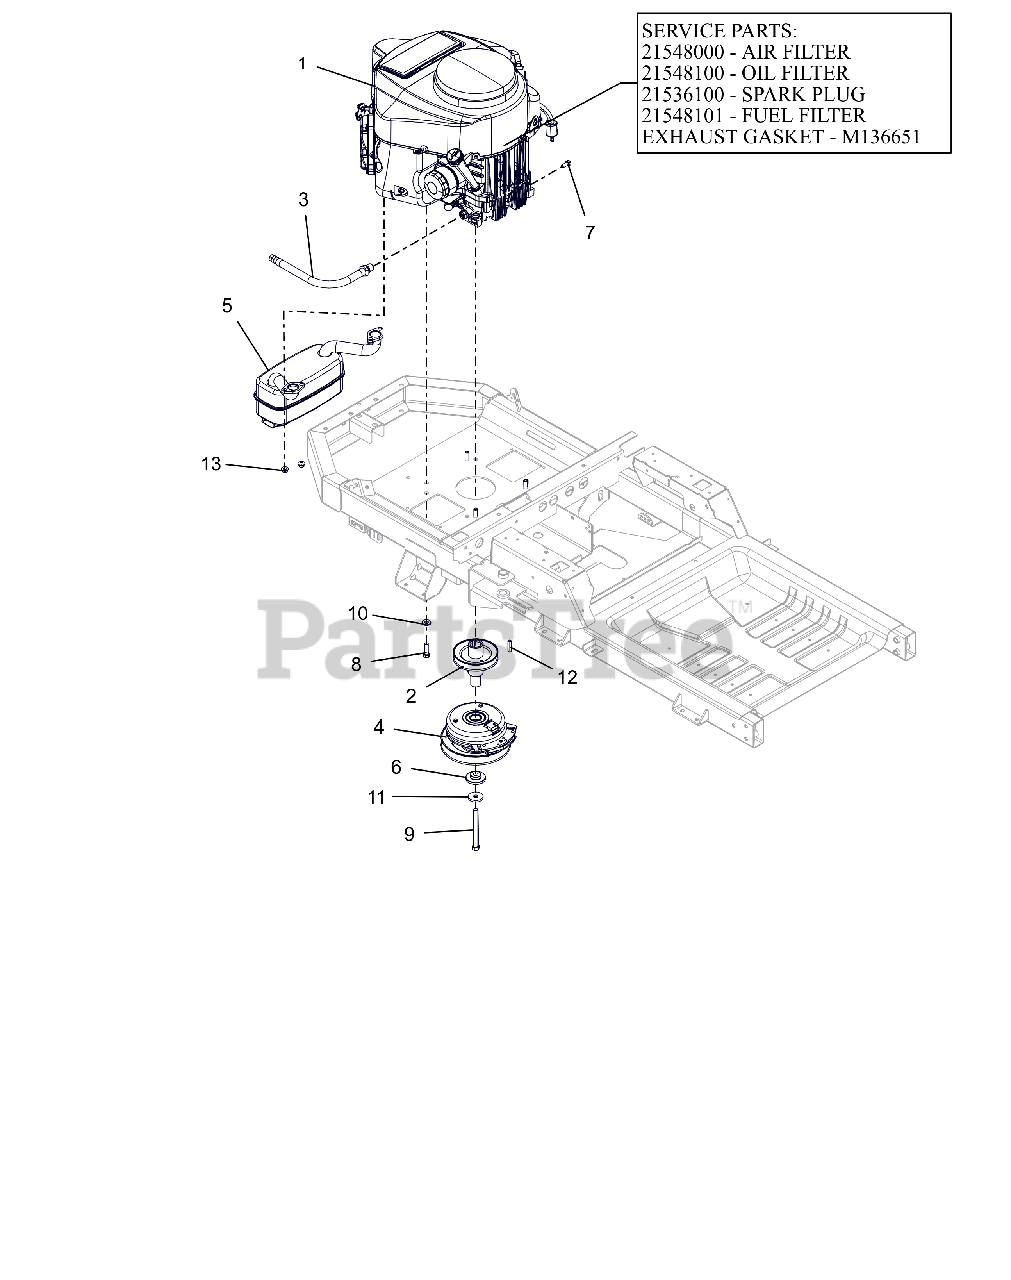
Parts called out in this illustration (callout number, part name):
1	ENGINE, KAWASAKI FR691 23HP
1	AIR FILTER, KAWASAKI FR
1	OIL FILTER, KAWASAKI FR
1	PLUG, SPARK
1	FUEL FILTER-KAWASAKI FR
1	GASKET, MUFFLER #
2	WLDMT, DRIVE SHEAVE-X
3	HOSE, OIL DRAIN
4	CLUTCH,105FTLB MONOPOLE 6.83"
5	MUFFLER - KAWASAKI
6	BSHG-FLG .469X1.06X.574X2.0
7	BLT, HEX M8-1.25X20 G8.8 ZCC
8	BLT, HEX .38-16X1.25 G5 ZCC NT
9	BLT, HEX .44-20X4.50 G8 ZCC NT
10	WASHER, 3/8" SPRING DISC
11	WASHER, 7/16" SPRING DISK
12	KEY-SQ .25 X 1.25 X .25 SAE
13	NUT-LK-TOP-FLG M8 ZCC
